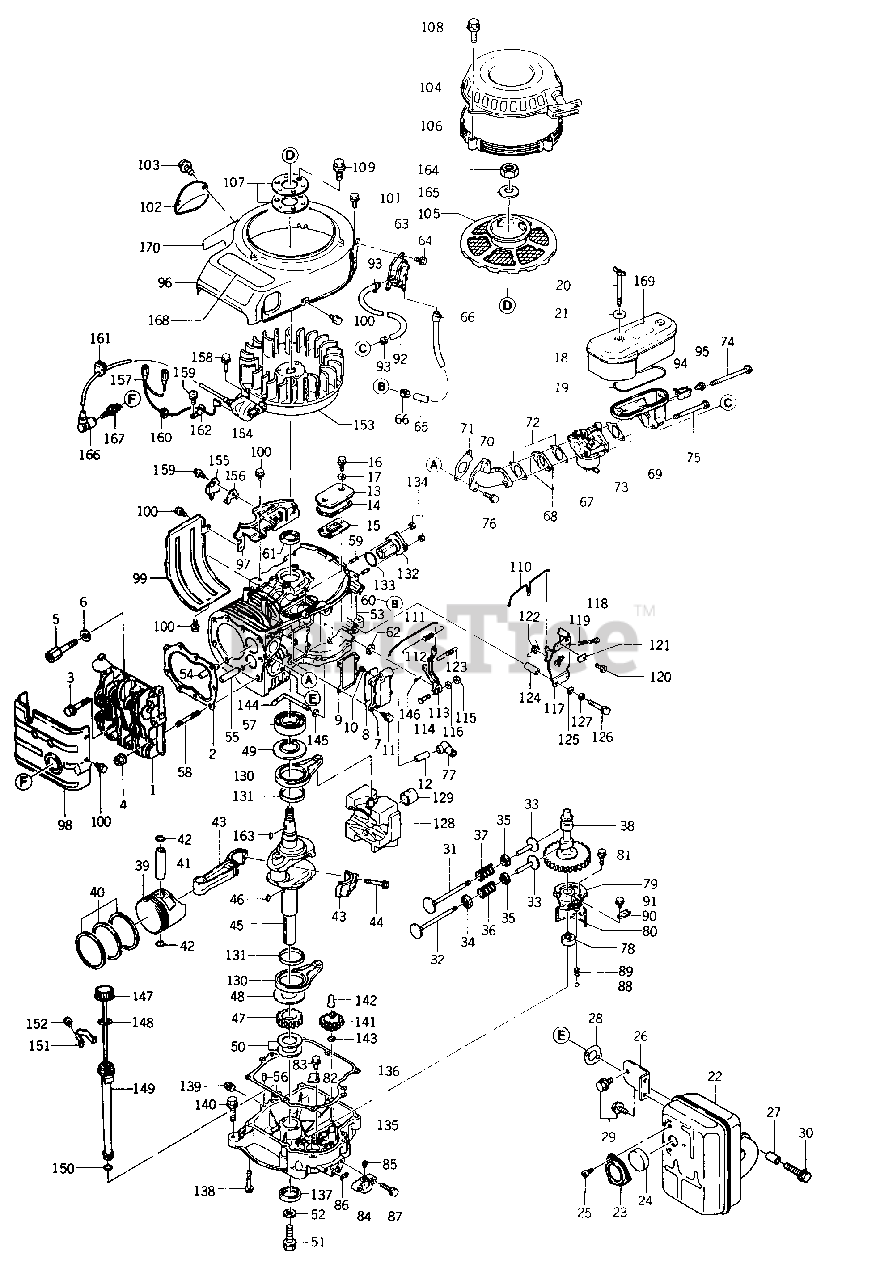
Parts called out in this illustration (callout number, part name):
1	HEAD, cylinder
2	GASKET, head
3	BOLT (10x55)
4	NUT (10mm)
6	WASHER
7	COVER, valve chamber
9	GASKET
10	SCREW
11	BOLT (6x16)
16	BOLT
17	GASKET
18	AIR FILTER ASS'Y
19	GASKET
22	MUFFLER ASS'Y
23	CAP
24	ARRESTER, spark
25	SCREW (5x8)
28	GASKET
29	BOLT (8x12)
30	BOLT (8x45)
31	VALVE, intake
32	VALVE, exhaust
35	RETAINER, spring
36	SPRING, valve
37	SPRING, valve
38	SHAFT, cam
39	PISTON
40	PISTON RING SET
41	PIN, piston
42	RING, snap
43	CONNECTING ROD ASS'Y
44	BOLT, connecting rod
45	CRANK SHAFT COMP
47	GEAR, helical
49	SPACER
50	SHIM
53	CRANK CASE COMP
54	GUIDE, valve (IN)
55	GUIDE, valve (EX)
56	PIN, dowel
57	BEARING, ball (6207)
61	SEAL, oil
62	SEAL, oil
63	FUEL PUMP ASS'Y
64	BOLT (6x10)
65	TUBE, braid
66	CLIP
67	CARBURETOR ASS'Y
69	PIPE, intake
70	PIPE, intake
71	GASKET
72	GASKET
73	GASKET
74	BOLT
76	BOLT (8x25)
78	OIL PUMP ASS'Y
79	PUMP COVER COMP
80	FILTER, oil
81	BOLT (8x25)
83	BOLT (5x8)
85	PLUG
87	BOLT (8x30)
88	BALL, steel
90	PLATE
91	BOLT (6x10)
92	TUBE, braid
93	CLIP
95	SCREW (5x8)
96	HOUSING, fan
97	HOUSING, fan
99	SHROUD
100	BOLT (6x10)
101	BOLT (6x14)
103	SCREW (4x8)
104	RECOIL STARTER ASS'Y
105	PULLEY
108	BOLT (6x35)
109	BOLT (8x12)
110	LINK, choke
111	LINK
113	GOVERNOR ARM COMP
115	NUT (6mm)
116	WASHER
117	CONTROL PANEL ASS'Y
118	SCREW (4x25)
119	SPRING
120	BOLT
123	SPRING
125	WASHER
126	BOLT (6x50)
127	WASHER, spring
128	WEIGHT COMP
129	BEARING, plain
130	ROD ASS'Y
131	BEARING, plane
134	NUT
135	CRANK CASE COVER COMP
136	GASKET
137	SEAL, oil
138	BOLT (8x45)
140	BOLT (8x25)
141	GOVERNOR ASS'Y
142	SLEEVE
143	WASHER
144	ARM, pivot
145	WASHER
146	PIN, snap
148	GASKET
150	O-RING
151	CLAMP
152	BOLT (5x8)
153	FLYWHEEL COMP
154	COIL, ignition
155	IGNITER
156	BRACKET
157	WIRE, lead
158	BOLT (5x25)
159	SCREW (4x8)
162	CLAMP
164	NUT (18mm)
166	CAP, spark plug
167	PLUG, spark (BMR4A)
168	LABEL, brand
169	LABEL, manual
170	LABEL, manual
